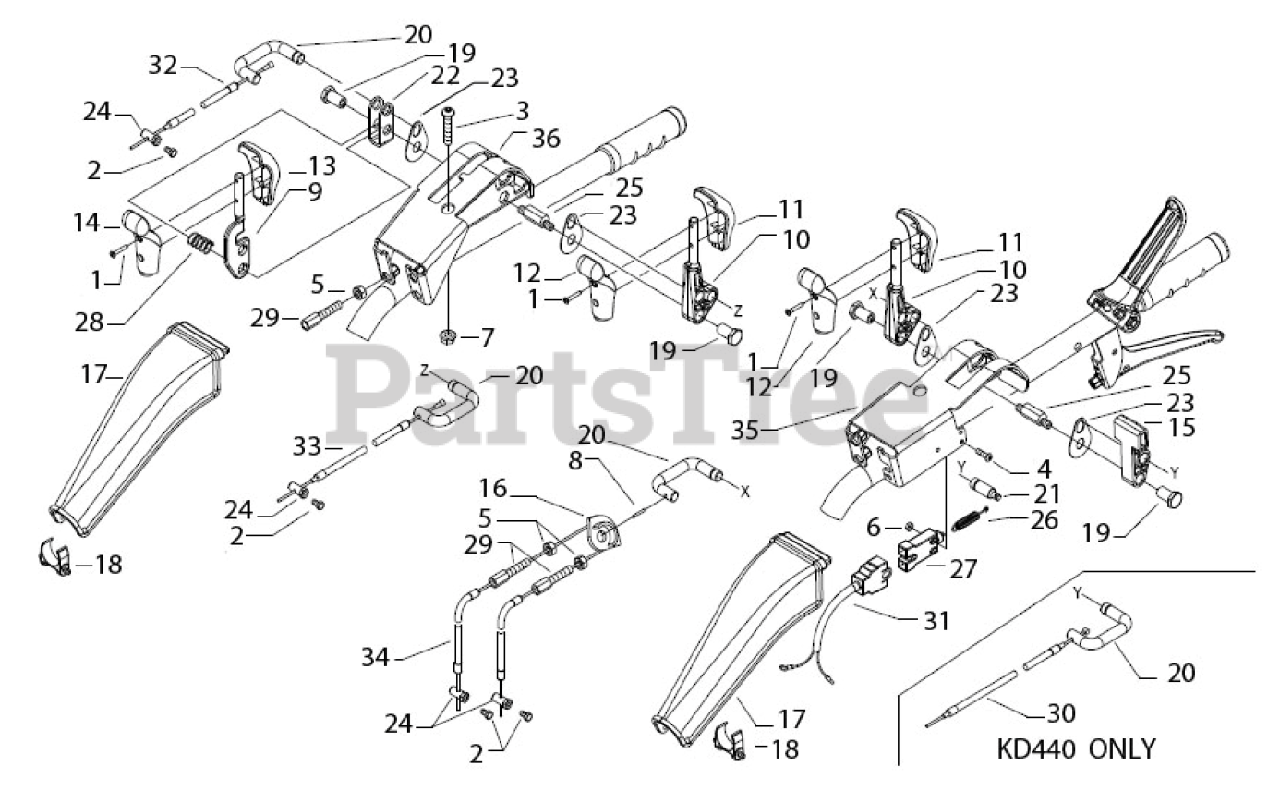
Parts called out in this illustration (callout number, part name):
1	SCREW 3,5X25
2	SCREW TE M6X16
3	SCREW TBCEI M8X40
4	SCREW TBCEI FL.M4X25
5	NUT M8
6	SELFLOCK NUT M4
7	SELFLOCK NUT M8
8	ROLL PIN 4X20 SPIROL
9	LEVER, FORWARD / REVERSE
10	LEVER, DIFFERENTIAL
11	UPPER HANDLE, HALF BLACK
12	LOWER HANDLE, HALF BLACK
13	UPPER HANDLE, HALF RED
14	LOWER HANDLE, HALF RED
15	LEVER, ON/OFF
16	PULLEY
17	COVER
18	CROSS PIECE
19	STUD BOLT
20	U BOLT
21	INDEXING BOLT
23	SMALL PLATE
24	CLAMPING SCREW
26	SPRING
27	SWITCH
28	SPRING
29	ADJUSTING SCREW
30	CABLE, FUEL CUT OFF KD440 ONLY
31	WIRING
32	CABLE, REVERSE
33	CABLE, DIFFERENTIAL
34	CABLE, PARKING BRAKE
35	SUPPORT LH
36	SUPPORT RH
